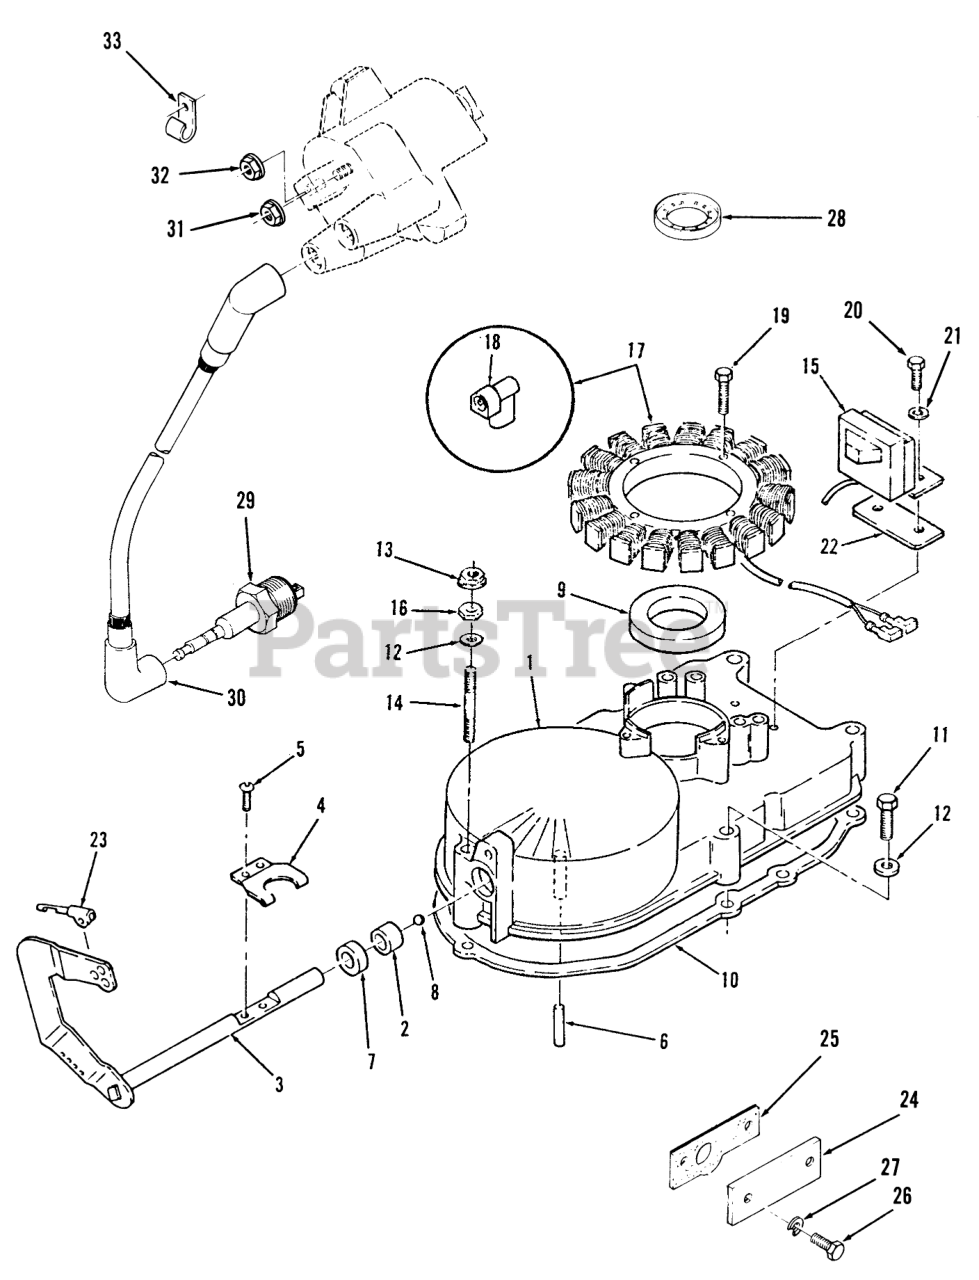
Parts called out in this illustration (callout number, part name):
1	Gearcase Kit (Includes Parts Marked )
2	Bearing
3	GOVERNOR-SHAFT & ARM
4	Yoke
5	Screw
6	Washer
7	Oil Seal
8	Bearing
9	Oil Seal
10	Gasket
11	HEX-HEAD CAP SCREW
12	Washer
13	Nut
14	Stud
15	Control-Ignition
16	Nut
17	Stator w/Terminals
18	RECEPTACLE TERMINAL
19	Bolt
20	Bolt
21	Lockwasher
22	Insulator
23	Retaining Clip
24	Plate
25	Gasket
26	Bolt
27	Washer
28	Rotor
29	Plug-Spark
30	Wire-Plug
31	Nut
32	Nut
33	Clip
